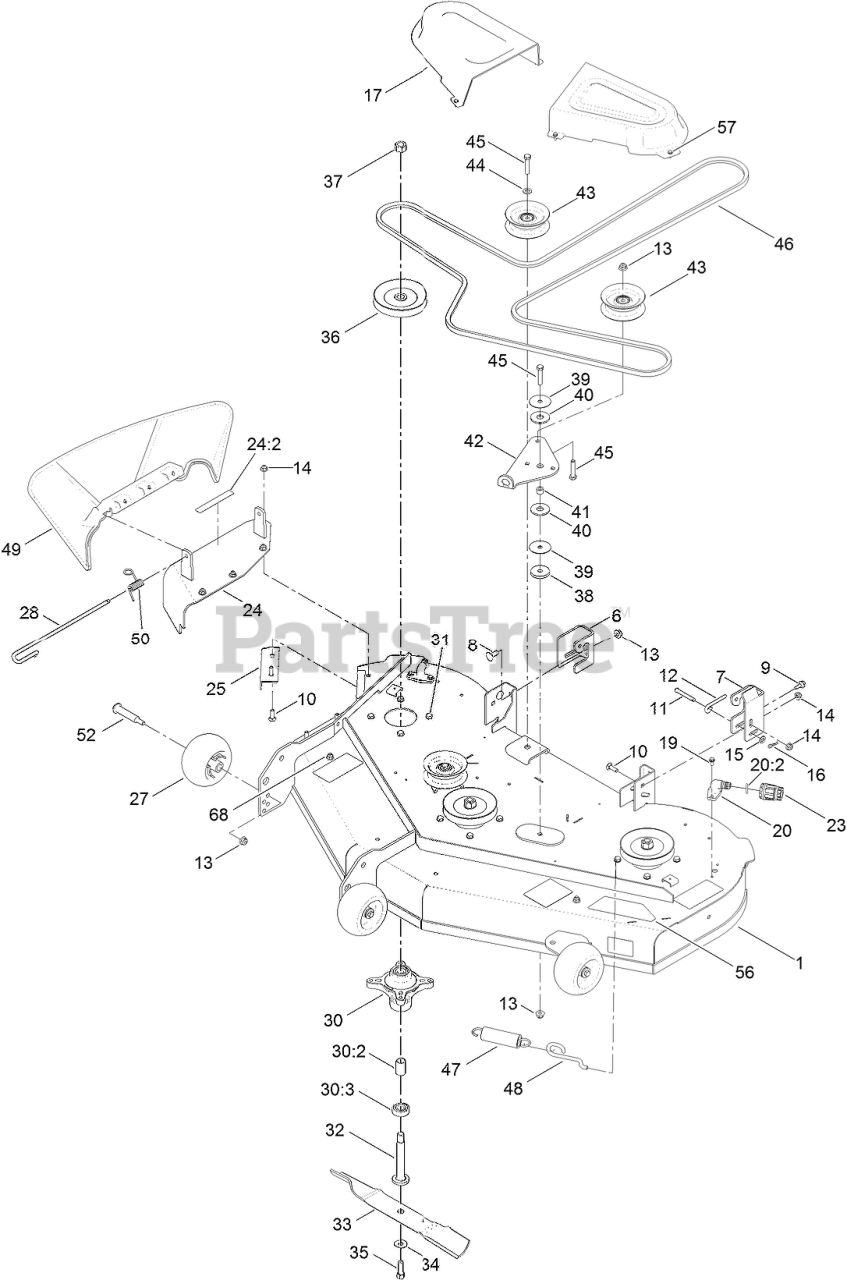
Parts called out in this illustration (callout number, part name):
1	DECK AND DECAL ASM
6	BRACKET-HANGER, RH
7	BRACKET-HANGER, LH
8	BOLT-CARR
9	SCREW-SHOULDER,HWH
10	SCREW-CARR
11	PIN-CLEVIS
12	ROD-LEVEL, DECK
13	NUT-HF, NI
14	NUT-HF, NI
15	WASHER-PLAIN
16	PIN-COTTER
17	COVER-BELT
19	SCREW-HWH
20	FITTING-WASHOUT
20:2	O-RING
23	CONNECTOR-HOSE
24	COVER ASM W/DECAL
24:2	DECAL-DANGER
25	BAFFLE-CUTOFF
27	ROLLER-SCALP, ANTI
28	PIN-CHUTE
30	SPINDLE ASM
30:2	SPACER
30:3	BEARING-BALL
31	SCREW-TAPTITE
32	SHAFT-SPINDLE
33	BLADE-HI LIFT
34	WASHER-BELLEVILLE
35	SCREW-HH
36	PULLEY
37	NUT-HEX
38	WASHER-PLAIN
39	WASHER
40	WASHER-FRICTION, COMPOSITE
41	SPACER
42	ARM-IDLER
43	PULLEY-IDLER, FLAT
44	WASHER-FLAT
45	SCREW-HH
46	V-BELT
47	SPRING-EXTENSION
48	HOOK-RETURN SPRING
49	DEFLECTOR-DISCHARGE
50	SPRING-TORSION
52	BOLT-SHOULDER
56	DECAL - DECK
57	SCREW-TAPTITE
68	SCREW-HH
